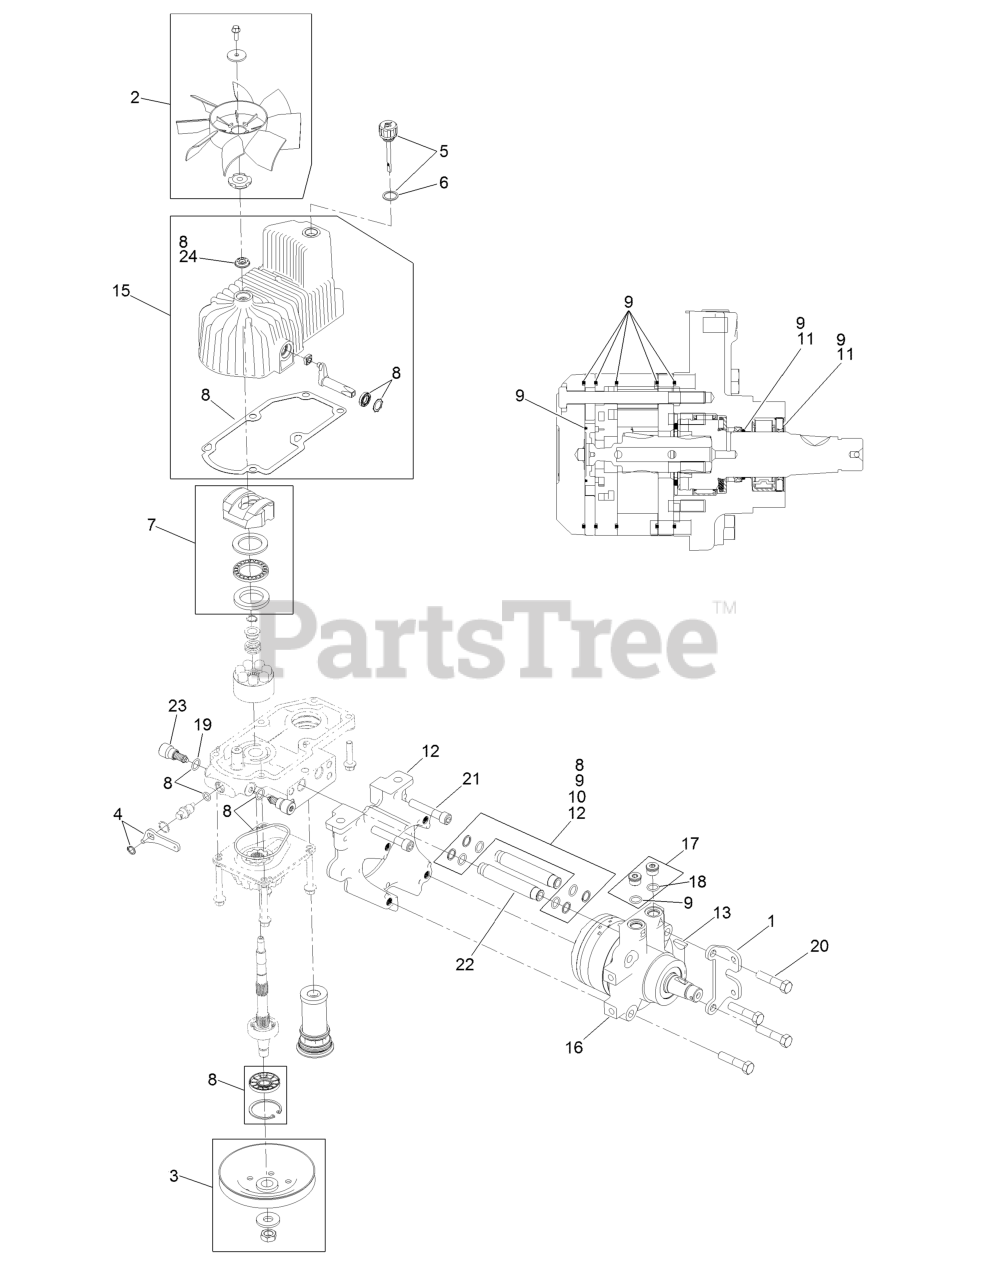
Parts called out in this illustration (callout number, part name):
1	Mount-Shoe, Horse
2	Fan Kit
3	Pulley Kit
4	Handle-Bypass Valve, Hydro
5	Dipstick-Hydro W/Gasket
6	Gasket-Dipstick, Hydro
7	Swash Block Kit
8	Pump Seal Kit
9	Motor Seal Kit
10	Tube Seal Kit
11	Output Shaft Seal Kit
12	Nose Cup-Uht
13	Key-Woodruff
15	Housing-RH
16	Motor-Hydraulic RH 240Cc
17	Magnetic Plugs Service Kit
19	O-Ring-Check Valve
20	Screw HH
21	Screw-HSH
22	Hydraulic Tube Kit
23	Shock Valve, 12Cc Hydro
24	Seal-Fan Drive
99	Puller-Pulley
99	Flow Test Kit
